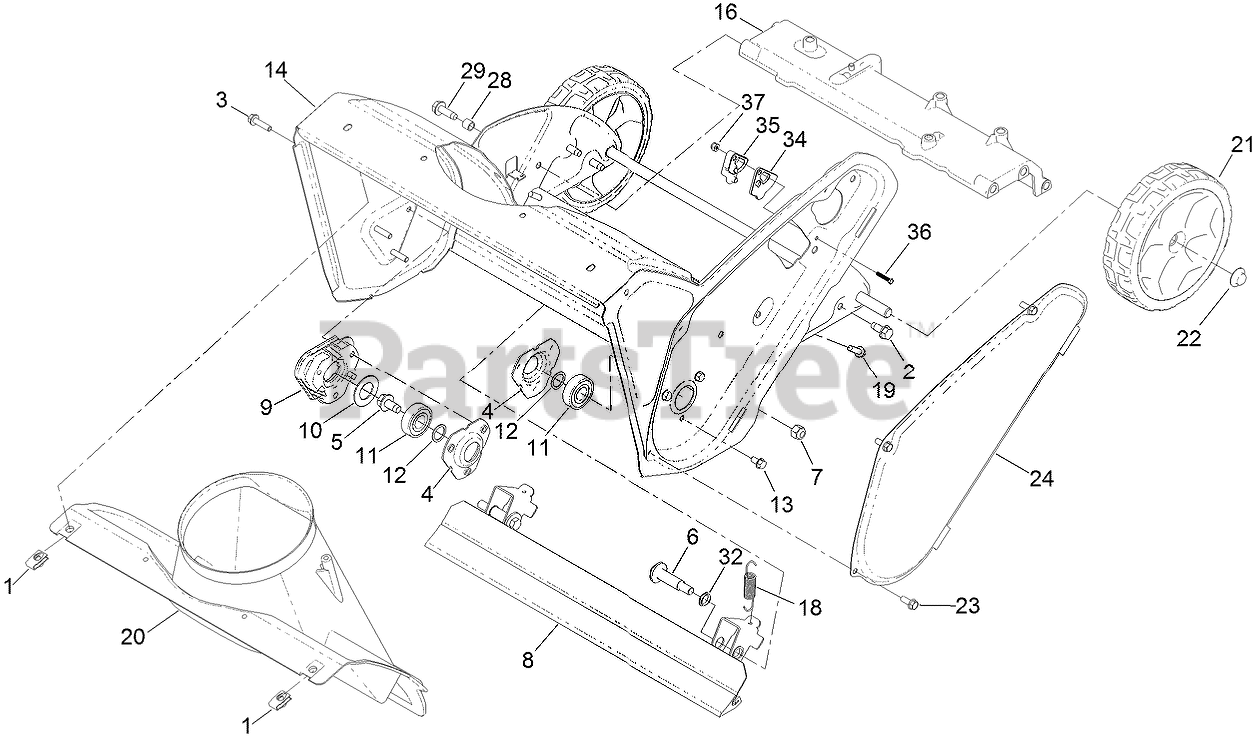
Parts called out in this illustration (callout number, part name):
2	SCREW-THD ROLL, HWH
3	SCREW-HWHTF
4	FLANGE-BEARING
5	SCREW-HWH
6	BOLT-SHOULDER
7	NUT-LOCK, NI
8	SCRAPER ASM
9	SPACER-BEARING, RH
10	WASHER-RUBBER
11	BEARING-BALL
12	WASHER-THRUST
13	SCREW-HWH
14	HOUSING-AUGER
16	BRACE-FRAME
18	SPRING-EXTENSION
19	SCREW-HWH
20	CHUTE-LOWER
21	WHEEL ASM, 7 INCH
22	NUT-PUSH
23	SCREW-HWH
24	COVER-BELT
28	SPACER-GROMMET
29	SCREW-HWHTF
32	BUSHING-NYLINER
34	CAP-GUIDE, CABLE
35	GUIDE-CABLE
36	Screw, Machine, Nozzle, 8-32 x 7/8"
37	NUT-HEX, NYLOCK
